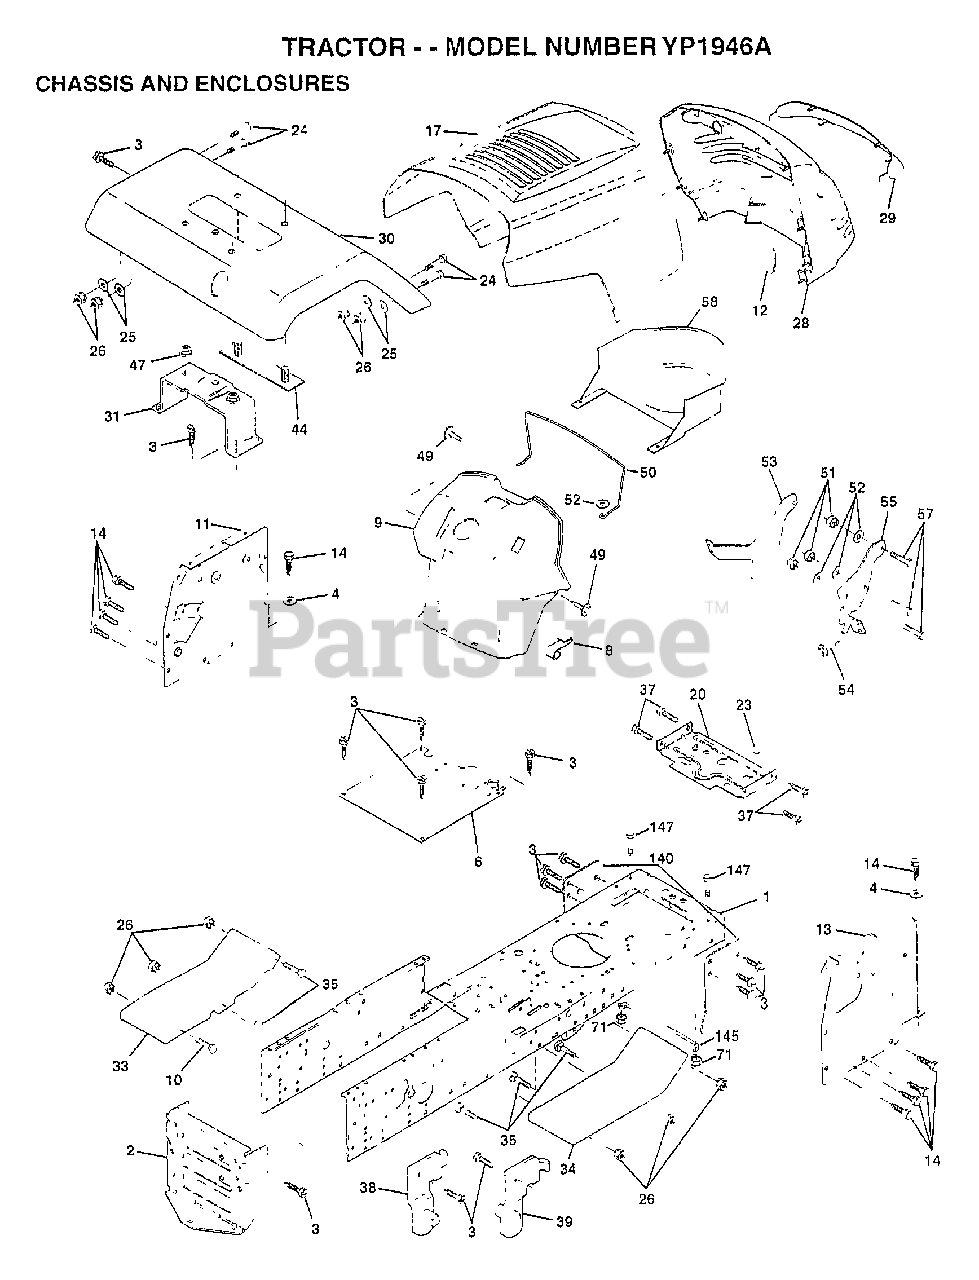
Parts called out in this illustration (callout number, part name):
1	CHASSIS ASM
3	SCREW
4	WASHER
6	SADDLE
8	"CLIP,INSULATOR"
9	DASH.PRVT.LBL.
11	PANEL DASH ASM
12	CLIP.TINNERMAN
13	"PANEL DASH,RH"
14	SCREW LT
20	"PLATE-MTG,BATT/FU"
24	BOLT
25	WASHER
26	NUT
28	GRILL
29	LENS.EURO.W/DECAL
30	"FENDER WS,FTK"
31	BRKT.ASM.FENDER
33	FOOTREST PNT LH
34	FOOTREST.RH.LT/GT
35	BOLT
37	SCREW LT
38	BRACKET ASM LH
39	BRACKET ASM RH
44	STRAP ASM FENDER
47	NUT-PUSH YT
49	SCREW HEX CRT
50	"ROD SUPPORT,DASH"
51	NUT
52	WASHER
53	BRACKET.GRILLE.LH
55	BRACKET.GRILLE.RH
140	BRKT SUSPENSION
145	"ROD POVOT,CHASSIS"
147	BOLT LT
